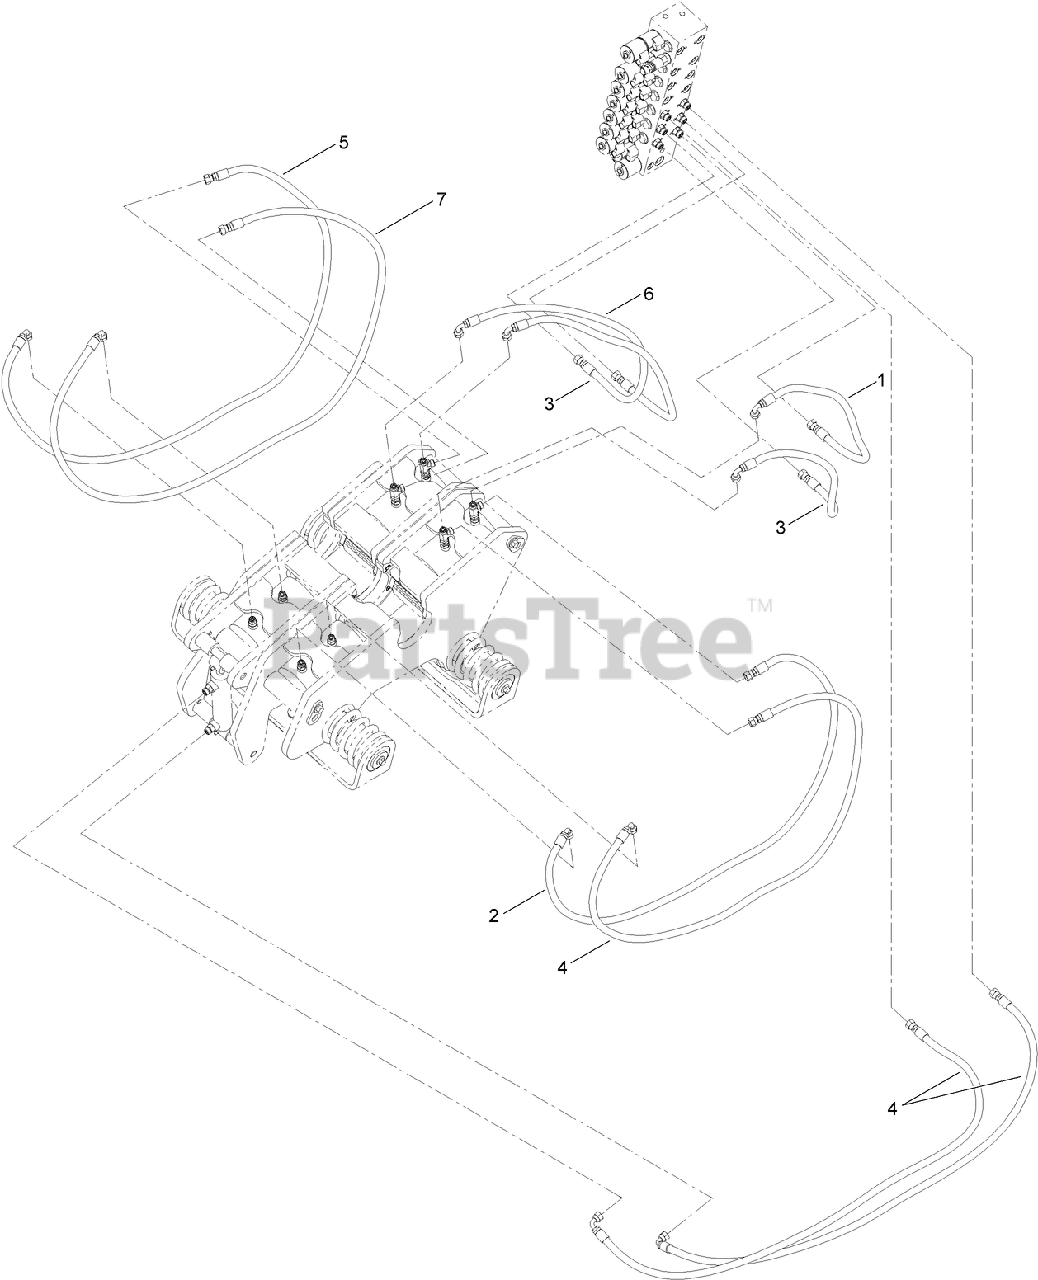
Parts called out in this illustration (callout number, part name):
1	HOSE ASM-HYD
2	HOSE ASM-HYD
3	HOSE ASM-HYD
4	HOSE ASM-HYD
5	HOSE ASM-HYD
6	HOSE ASM-HYD
7	HOSE ASM-HYD
